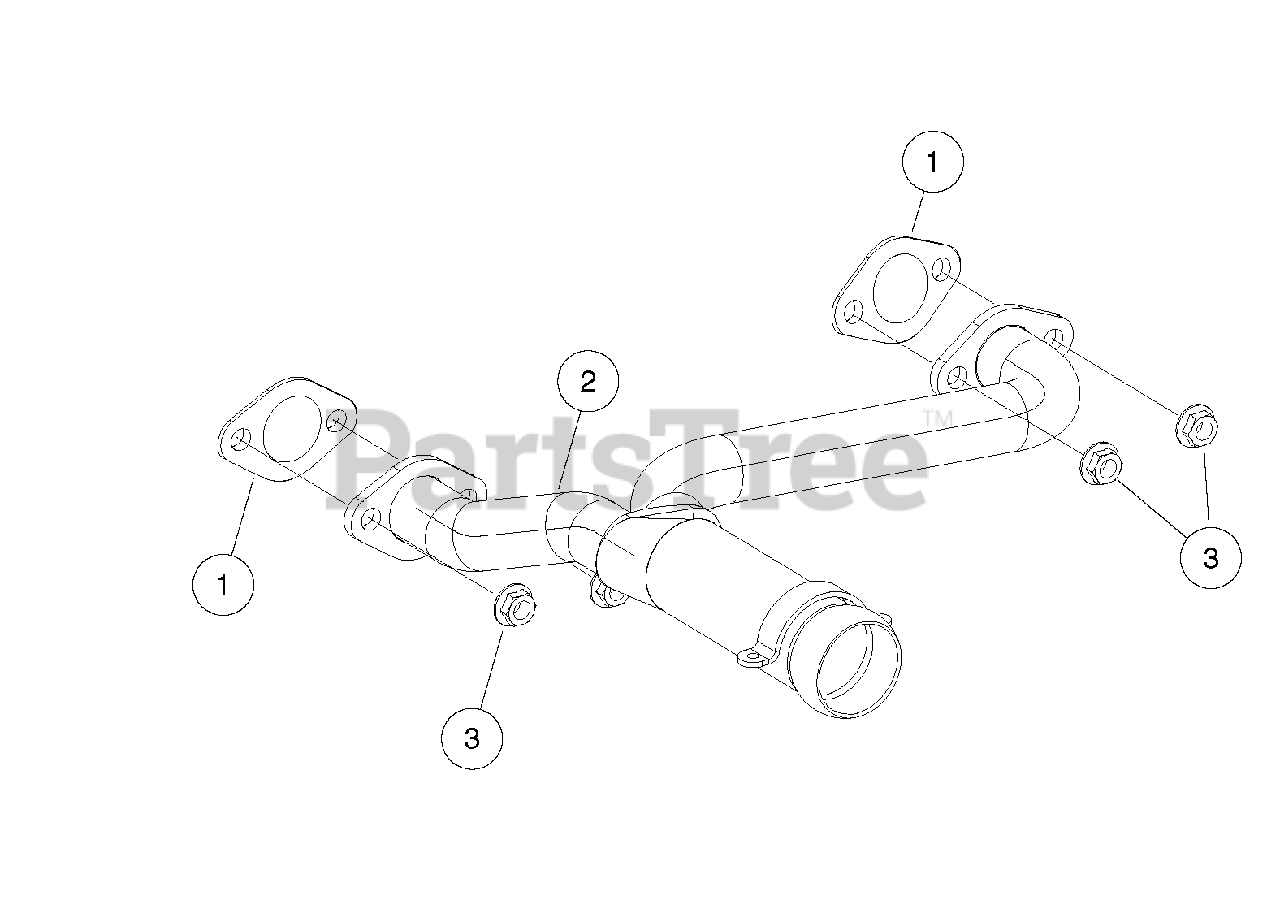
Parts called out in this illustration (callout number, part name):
1	Gasket, Exhaust Header, Fh680d
2	Header, Exhaust, Gas, Fh680d
3	Nut Flg, M8 X 1.25 Serrated
